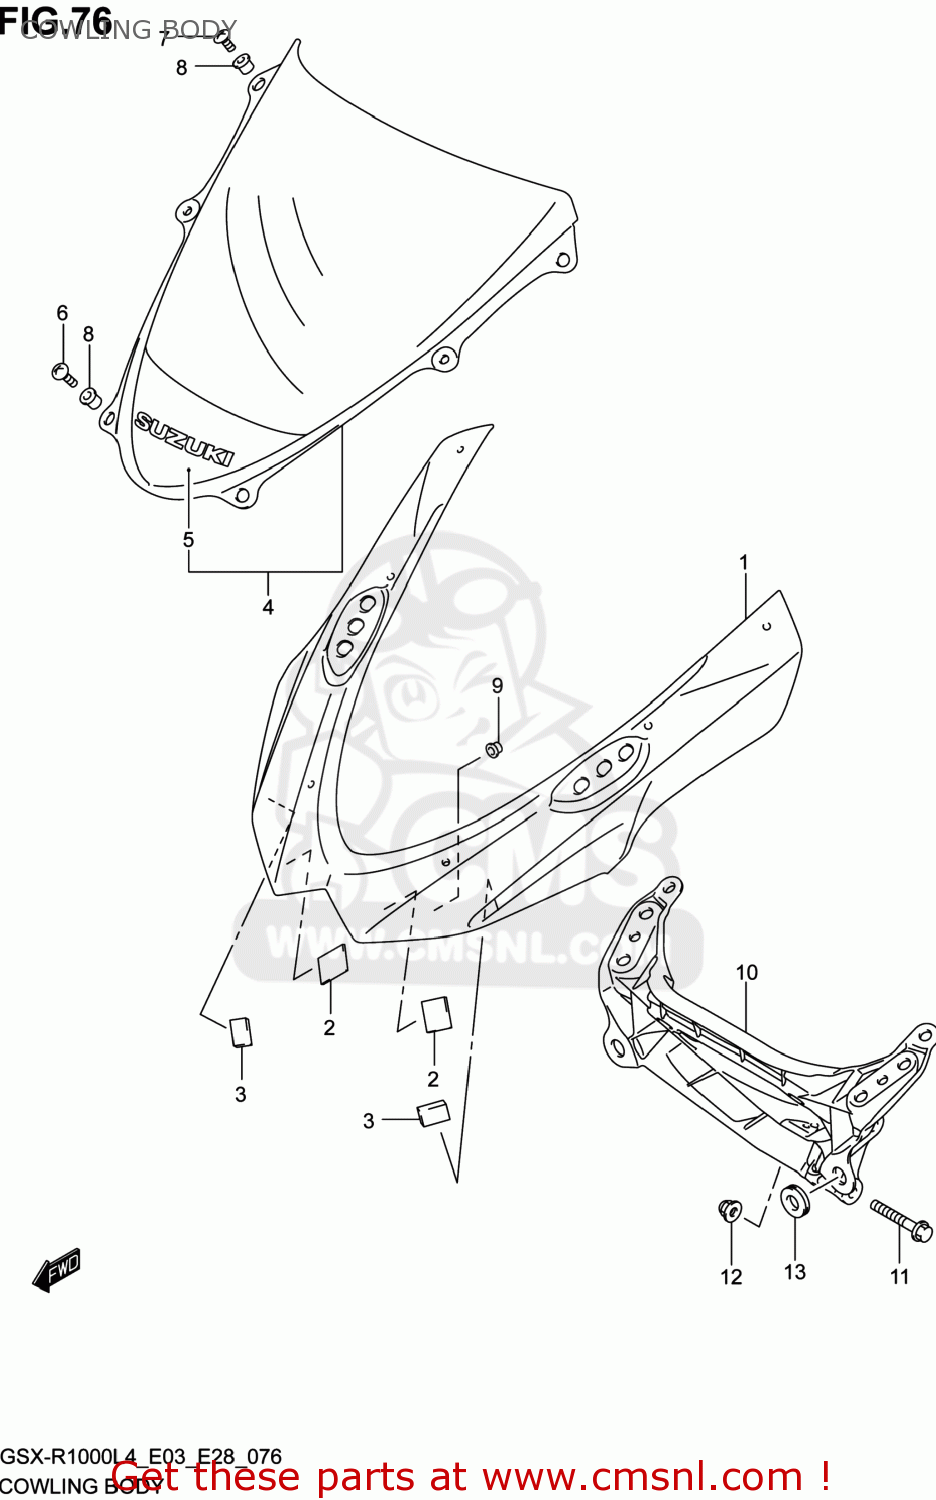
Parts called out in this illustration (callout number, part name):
1	BODY,COWLING
2	FASTENER
3	FASTENER,COWLING
4	WINDSCREEN
5	TAPE,WINDSCREEN
6	SCREW(5X18)
7	SCREW(5X15)
8	NUT
9	CUSHION
10	BRACE,COWLING
11	BOLT
12	NUT
13	CUSHION
